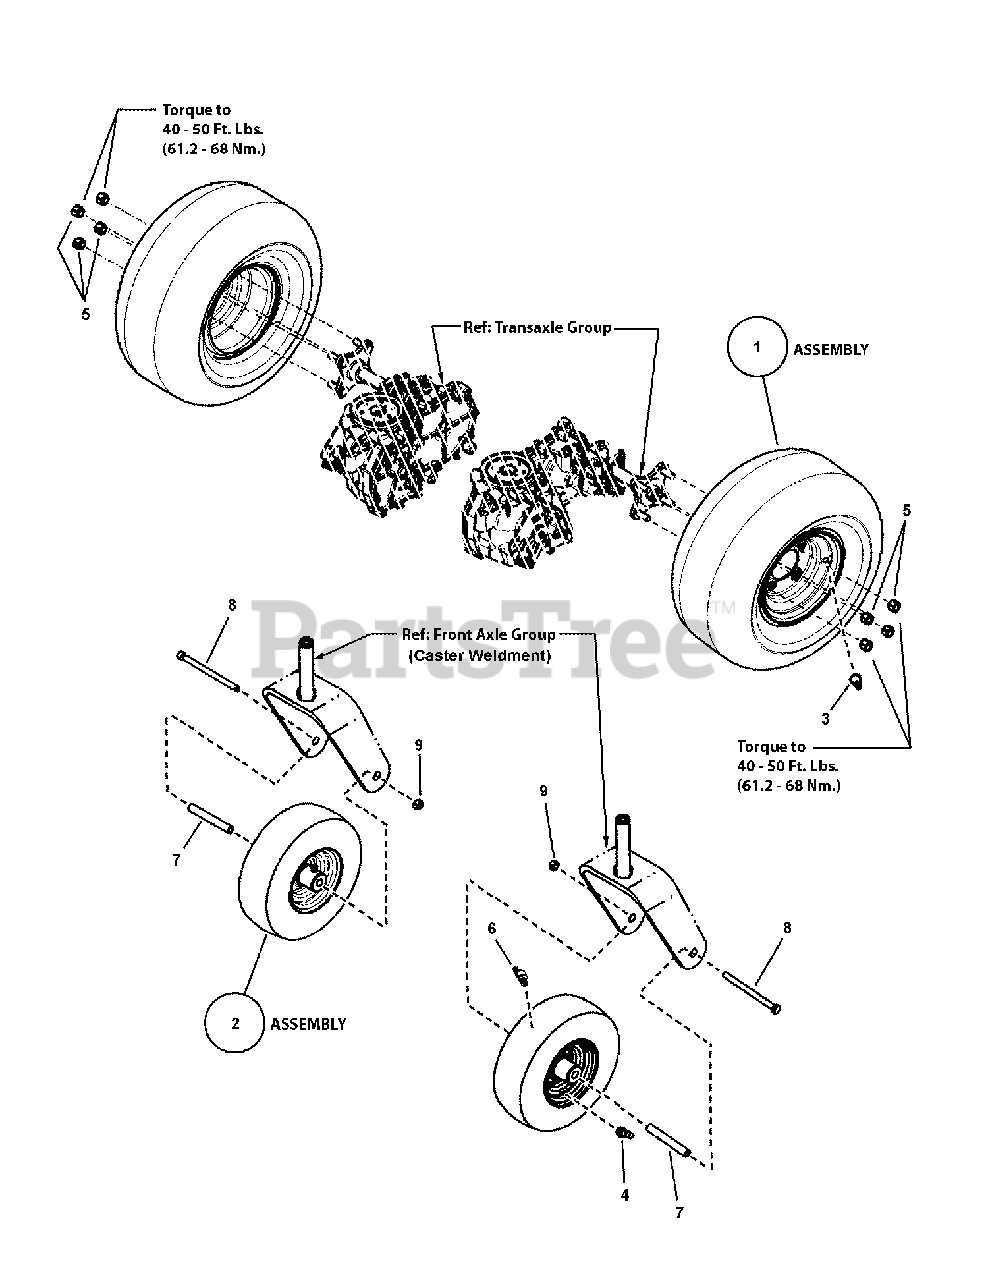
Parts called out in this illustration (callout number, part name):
1	ASSEMBLY, Rear Wheel & Tire, 18 x 9.50-8, K500, PMS 877
3	VALVE STEM & CAP, AIR, .453" DIA, 1.0" LG
4	VALVE STEM & CAP, AIR, .453" DIA, 0.88" LG
5	LUG NUT, 1/2 - 20 Tapered Seat, YZ
6	GREASE FITTING, (8M x 1 threads, 45 degree)
7	TUBE, Caster Wheel, 0.625 OD 4.53 OLG 0.625 OD
8	SCREW, 7/16-14NC x 6", Hex Head Cap, GR 5, YZ
9	NUT, 7/16-14 Hex Center Lock, GR 5 or B
